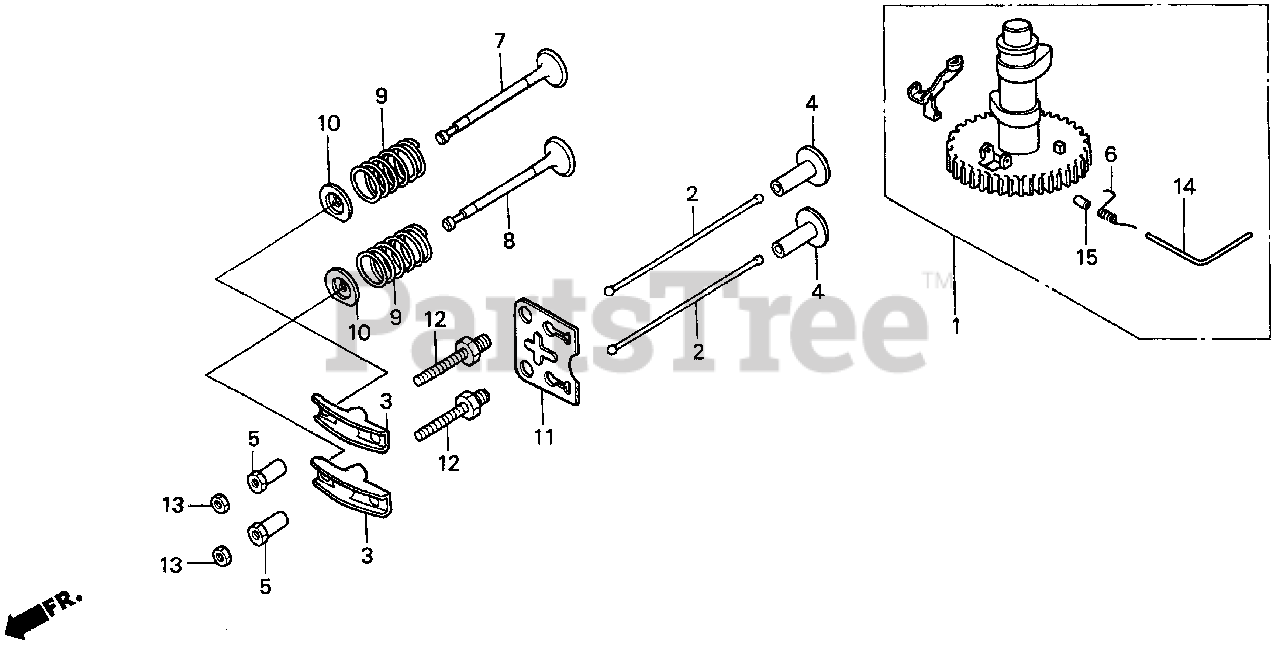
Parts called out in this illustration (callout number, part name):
1	CAMSHAFT ASSY.
2	ROD, PUSH
3	ARM, VALVE ROCKER
4	LIFTER, VALVE
5	PIVOT, ROCKER ARM
6	SPRING, WEIGHT RETURN
7	VALVE, IN.
8	VALVE, EX.
9	SPRING, VALVE
10	RETAINER, IN. VALVE SPRING
11	PLATE, PUSH ROD GUIDE
12	BOLT, PIVOT (8MM)
13	NUT, PIVOT ADJ.
14	PIN, WEIGHT CENTER
15	COLLAR, WEIGHT CENTER
